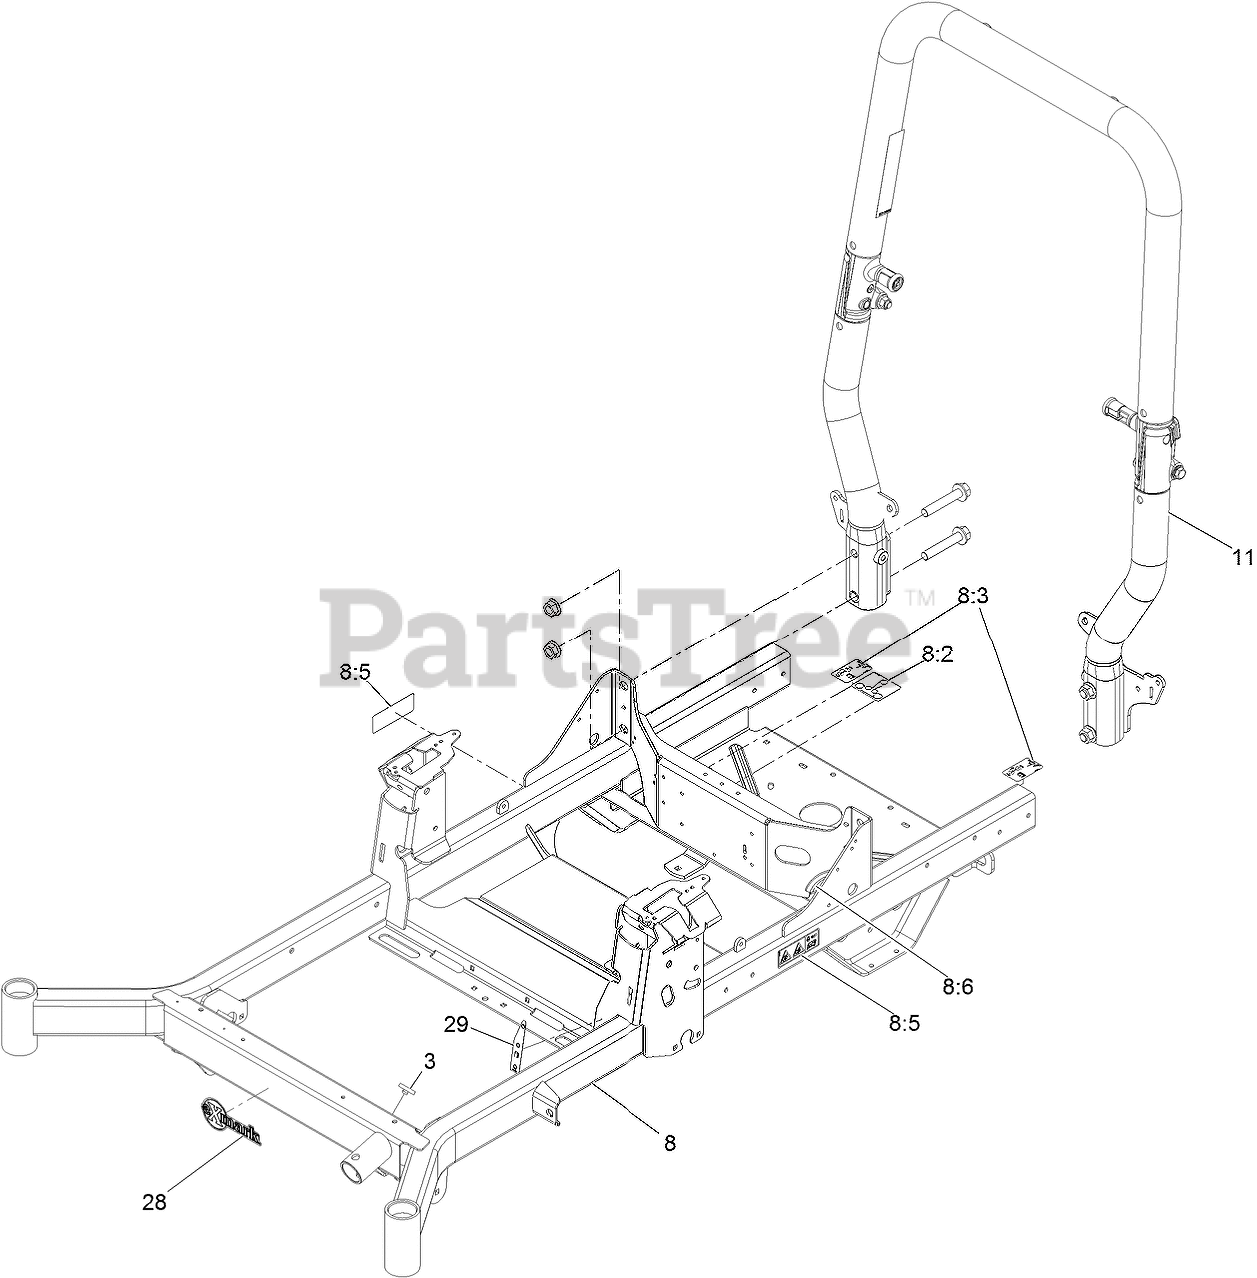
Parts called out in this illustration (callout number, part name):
3	BUMPER-PUSH-IN, RUBBER
8	Frame-60, Suspension
8:2	DECAL-ROUTING, BELT
8:3	DECAL-RELEASE, DRIVE
8:5	DECAL-WARNING
8:6	STRIP-SEAL
11	ASM-ROPS TAPERED
28	DECAL-EXMARK LOGO
29	DECAL-FILL, FUEL
